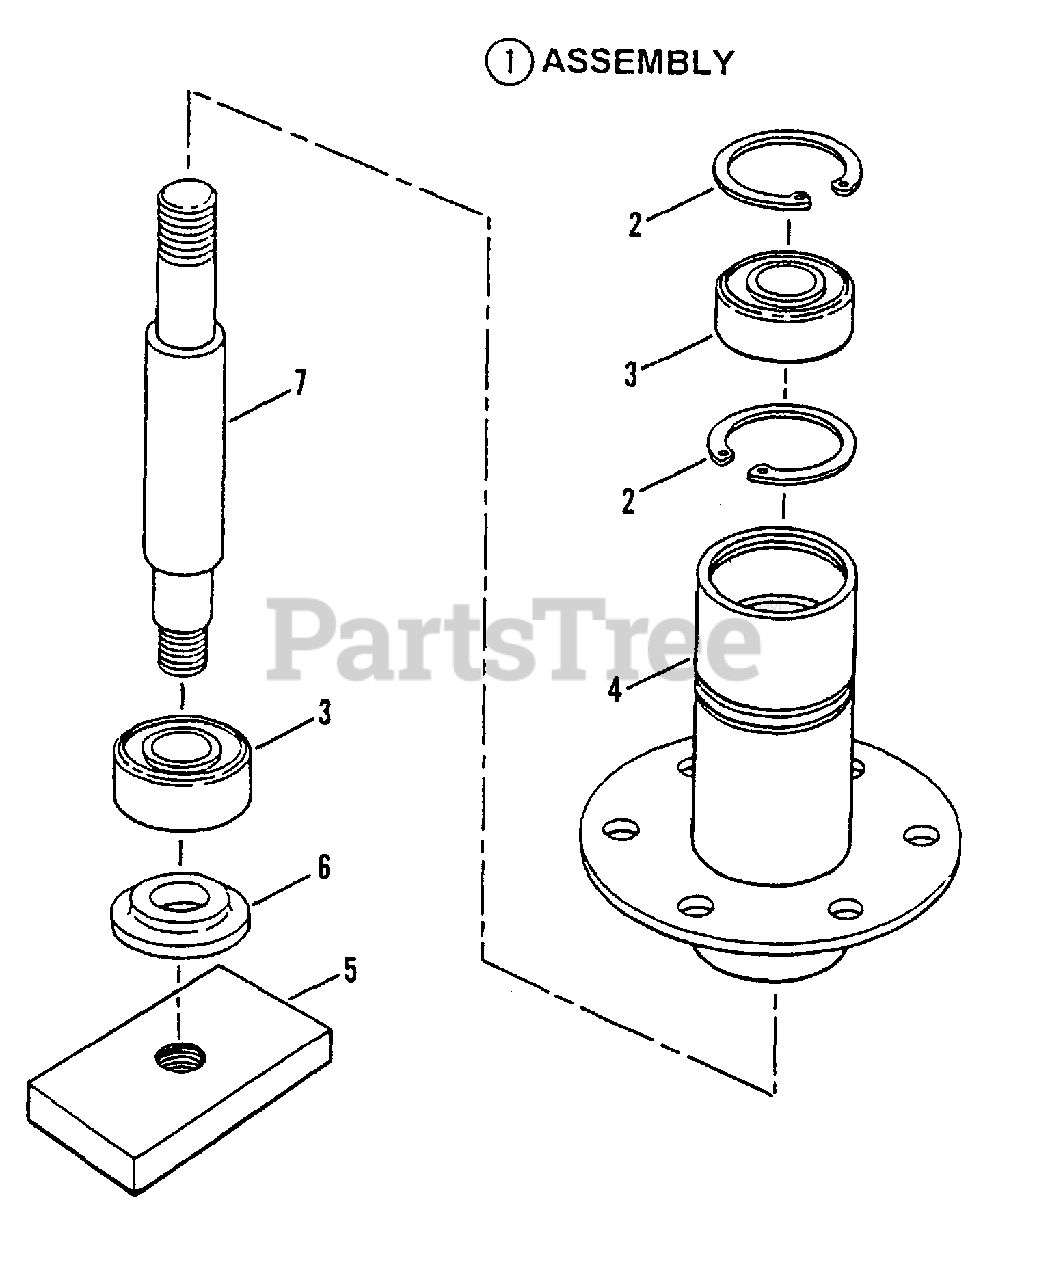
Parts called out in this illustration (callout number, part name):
1	ASSEMBLY, Spindle Housing, 42" Cutting Deck
2	RING, Retaining 1-3/4"
3	BEARING, Spindle
4	HOUSING, Spindle
5	HOLDER, Blade
6	WASHER, Spindle
7	SPINDLE 6.5"
